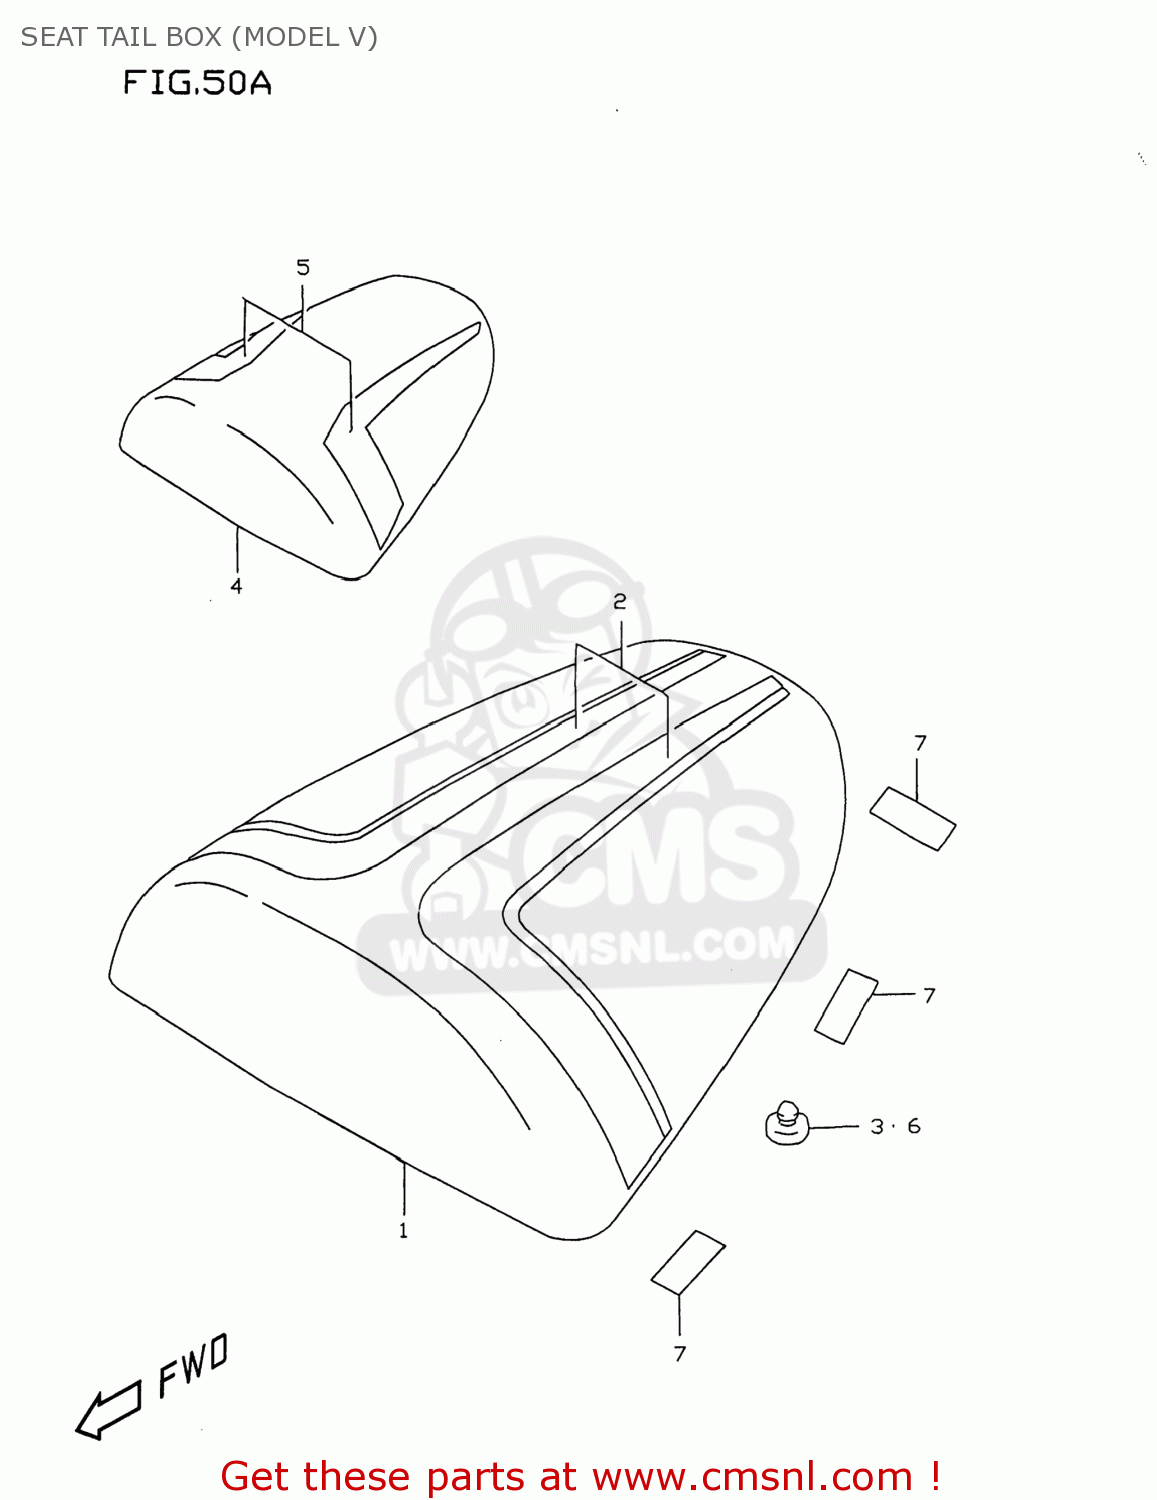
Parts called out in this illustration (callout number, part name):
1	BOX ASSY,SEAT TAIL(WHITE)
2	TAPE SET,BOX SEAT TAIL
3	CUSHION(11.5X22X20)
4	BOX ASSY,SEAT TAIL(ORANGE)
5	TAPE SET,BOX SEAT TAIL
6	CUSHION(11.5X22X20)
7	PROTECTOR SET,SEAT TAIL BOX
